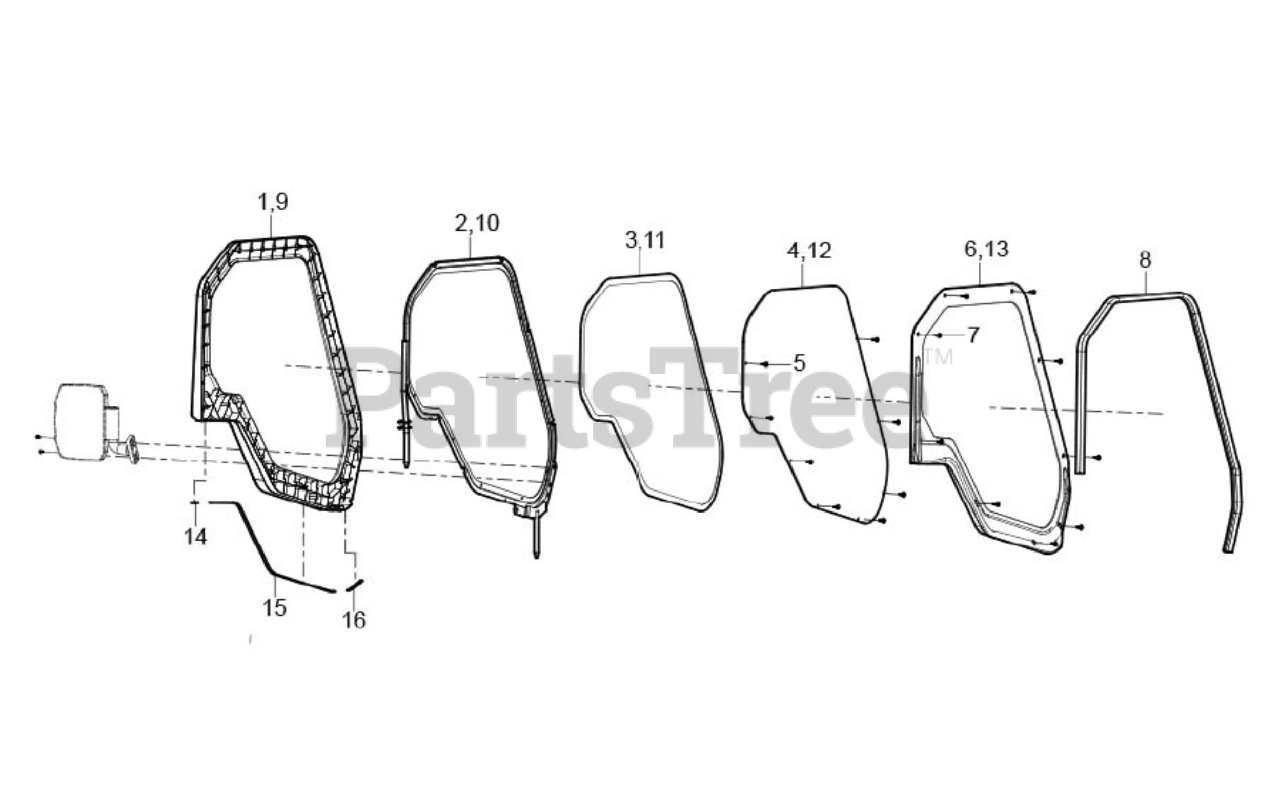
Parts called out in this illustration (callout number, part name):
1	DOOR PROTECTOR - LEFT OUTSIDEII
2	UPPER DOOR SEAT
3	SEAL - DOOR WINDSHIELD - LEFT
4	WINDSHIELD DOOR - LEFT
5	HEXAGON SOCKET HEAD CAP SCREWS M5X12
6	DOOR PROTECTOR - LEFT INSIDE
7	HEXAGON SOCKET HEAD CAP SCREWS M4X12
8	SEAL - FRONT WINDSHIED
9	DOOR PROTECTOR - RIGHT OUTSIDE
10	DOOR FRAME KIT - RIGHT
11	SEAL - DOOR WINDSHIELD - RIGHT
12	WINDSHIELD DOOR - RIGHT
13	DOOR PROTECTOR - RIGHT INSIDE
14	SIDE WINDSHIELD GASKET 3
15	SIDE WINDSHIELD GASKET 4
16	SIDE WINDSHIELD GASKET I2
